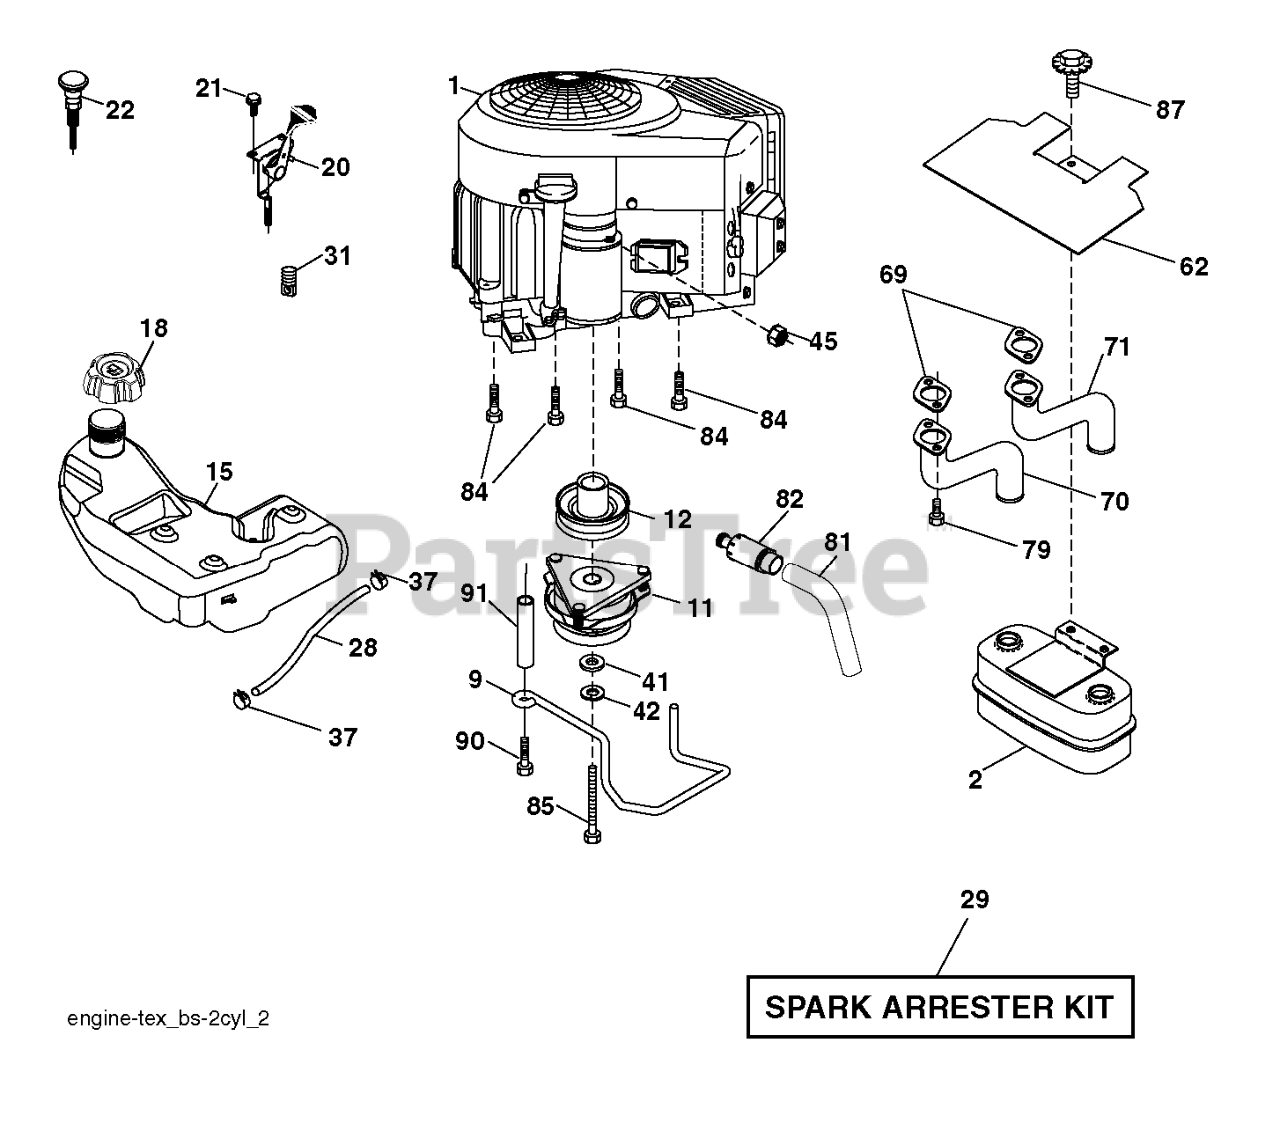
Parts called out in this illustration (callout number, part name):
2	MUFFLER.TWIN.CYL.LOW.TONE
9	KEEPER.BELT.ENGINE.4.2
11	CLUTCH MZ ZTR GT.48/54"1.125"
12	PULLEY ENGINE
15	TANK.FUEL.4GAL
18	CAP.FUEL.TANK.3"GREY
20	THROTTLE CABLE
21	SCREW.#10 X 0.750.BOS
22	CONTROL.CHOKE.ERGO.PUSH-IN.BLA
28	LINE.FUEL.64"REAR.EMIS
29	KIT.SPARK ARRESTOR 794945 B&S
37	HOSE CLAMP
42	LOCKWASHER
45	NUT
62	RP SHIELD HEAT MUFFLER
69	GASKET.MUFFLER
70	RP.EXHAUST.TUBE.LH.BS/TWIN
71	EXHAUST.TUBE.RH.BS/TWIN
79	SCREW.SOCKET.HEAD.5/16-18
81	TUBE, DRAIN OIL ASM.
82	PLUG DRAIN OIL EASY
84	SCREW.3/8-16
85	BOLT HEX 7/16-20 X 3.75 GR. 5
87	BOLT.5/16-18UNCX1.W/SEMS.BLK
90	SCREW 3/8-16X1
91	BUSHING.1.375OD
